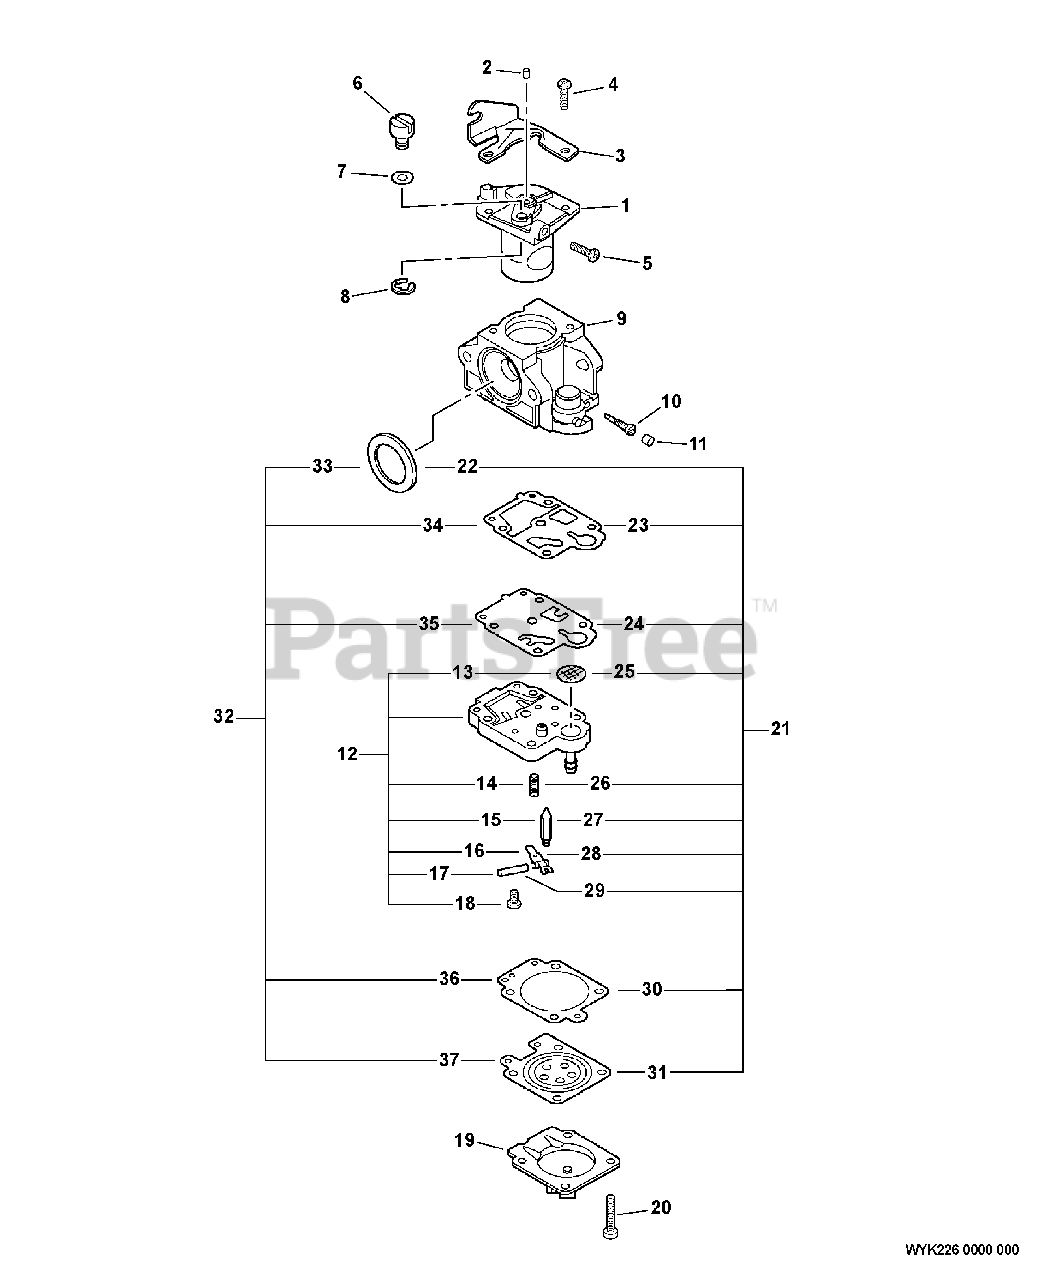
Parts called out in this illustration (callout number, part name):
1	THROTTLE VALVE ASSY
2	CAP, LIMITER
3	BRACKET, CABLE
5	SCREW, IDLE ADJUST
8	RING, RETAINING
9	BODY, CARBURETOR
10	NEEDLE - HIGH SPEED
11	CAP, LIMITER
12	PUMP BODY ASSY
13	STRAINER
14	SPRING, METERING LEVER
15	VALVE, INLET NEEDLE
16	LEVER, METERING
17	PIN, METERING LEVER
18	SCREW, METERING LEVER PIN
19	COVER, PRIMER PUMP
21	REPAIR KIT
22	SEAL
23	GASKET, PUMP
24	DIAPHRAGM, PUMP
25	STRAINER
26	SPRING, METERING LEVER
27	VALVE, INLET NEEDLE
28	LEVER, METERING
29	PIN, METERING LEVER
30	GASKET, DIAPHRAGM
31	DIAPHRAGM, METERING
32	DIAPHRAGM/GASKET KIT
33	SEAL
34	GASKET, PUMP
35	DIAPHRAGM, PUMP
36	GASKET, DIAPHRAGM
37	DIAPHRAGM, METERING
